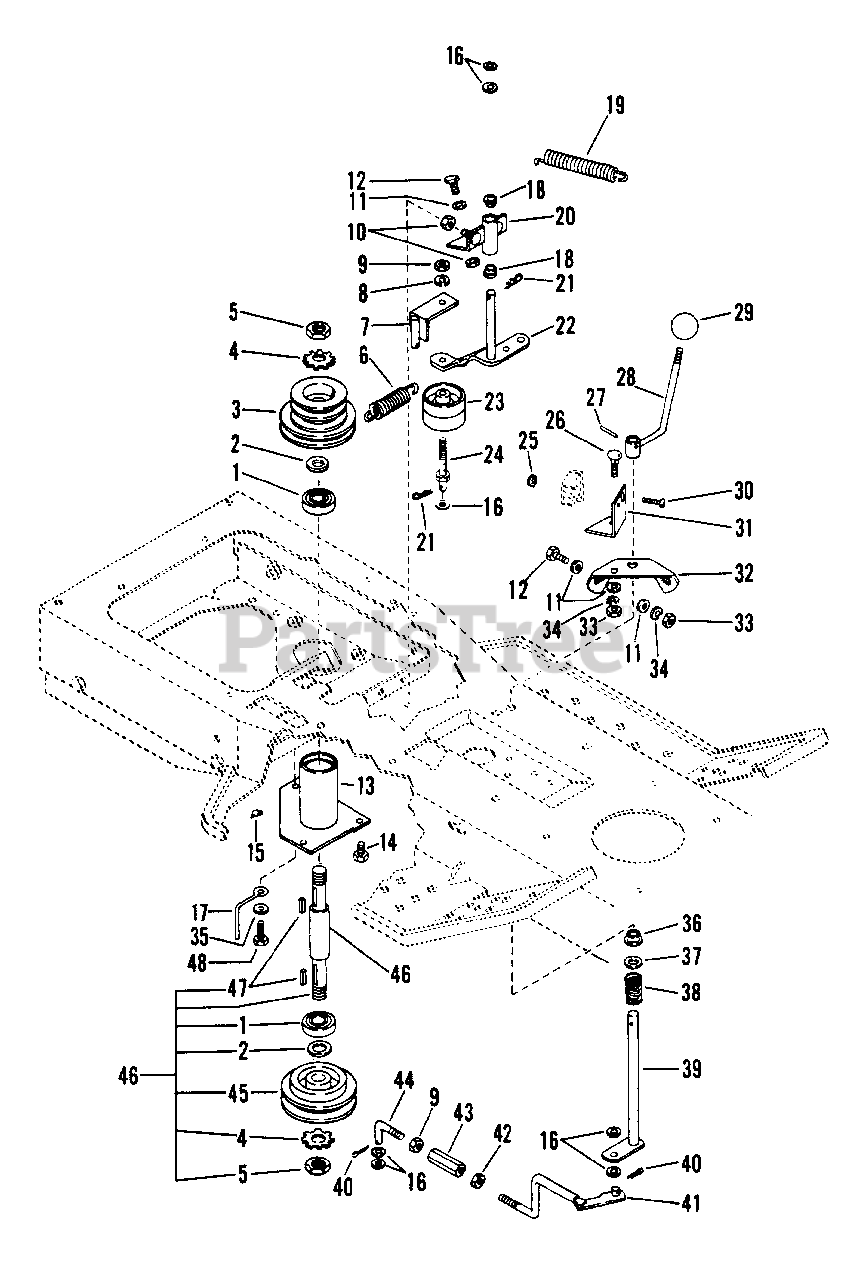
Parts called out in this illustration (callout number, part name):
1	BEARING, RADIAL
2	WASHER, FLAT .812X1.496X.134
3	SHEAVE, DOUBLE GROOVE
4	LOCKWASHER, INTERNAL 3/4
5	NUT, JAM 3/4-10 HEX
6	SPRING, DRIVE
7	BRACKET
8	WASHER, LOCK 3/8 REG.
9	NUT, HEX 3/8-16
10	NUT, LOCK 5/16-18
11	WASHER, FLAT .312X.734X.065
12	BOLT, HEX 5/16-18X.75
13	HOUSING, SPINDLE
14	BOLT, HEX 5/16-18X1.50
15	FITTING, ZERK
16	WASHER, FLAT .406X.812X.065
17	FINGER, BELT
18	BUSHING, FLANGE
19	SPRING
20	PIVOT, IDLER
21	HAIRPIN, INTERNAL 3/32
22	ARM, IDLER
23	IDLER, ATTACHMENT
24	BOLT, IDLER MOUNTING
24	BOLT, HEX 3/8-16X1.75
25	NUT, KEPS 10-24
26	BOLT, CARRIAGE 5/16-18X.75
27	PIN, SPRING .187X1.250
28	HANDLE, PTO
29	KNOB, ADJUSTMENT CONTROL
30	SCREW, MACHINE 10-24X1.00 RHD
31	BRACKET, SWITCH
32	BRACKET
33	NUT, HEX 5/16-18
34	WASHER, LOCK 5/16 SP
35	WASHER, FLAT .344X.688X.065
36	BUSHING, FLANGE
37	WASHER, FLAT .500X1.250X.083
38	SPRING, COMPRESSION
39	LEVER, PTO
40	PIN, COTTER .125X1.00
41	LINK, IDLER
42	NUT, HEX 3/8-16 L.H.
43	NUT, COUPLING
44	LINK, IDLER ADJUSTER
45	SHEAVE, JACKSHAFT
46	SHAFT
47	KEY, STRAIGHT SAE 1035
48	BOLT, HEX 5/16-18X1.00
